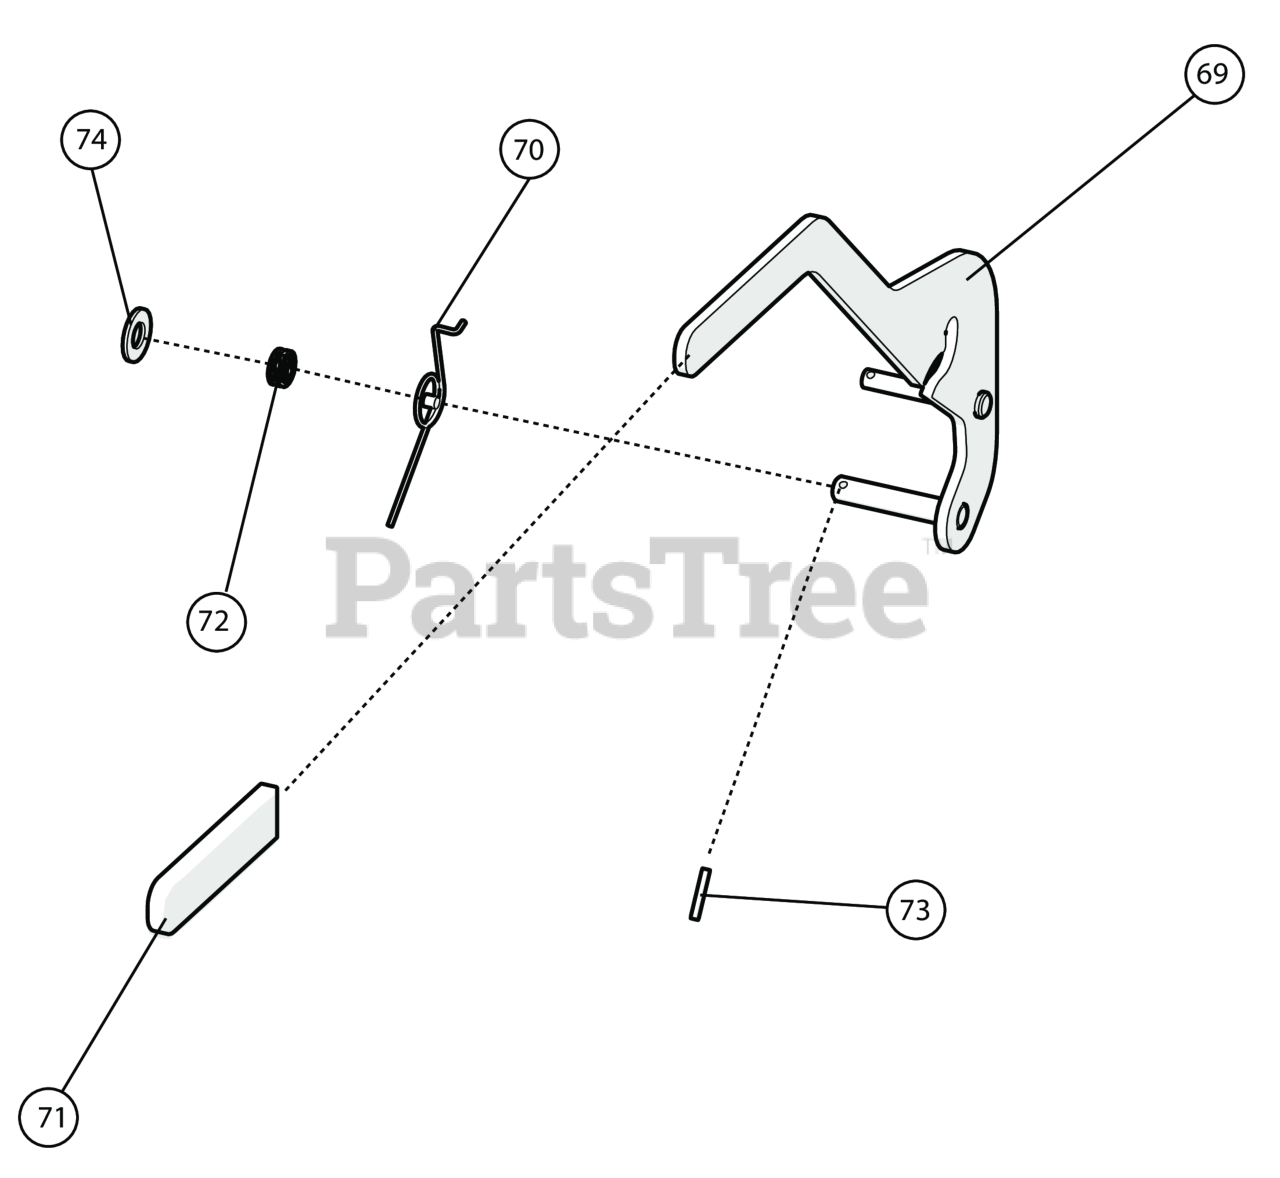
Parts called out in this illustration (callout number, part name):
69	WA, TRANSPORT LOCK
70	SPRING TRANS IDLER
71	GRIP, DRIVE HANDLE
72	WAVE SPRING, .58 X .75 X .250 THK
73	PIN, ROLL, .156 X 1.00 LG., ZP
74	WASHER 1/2" SAE Z/P
